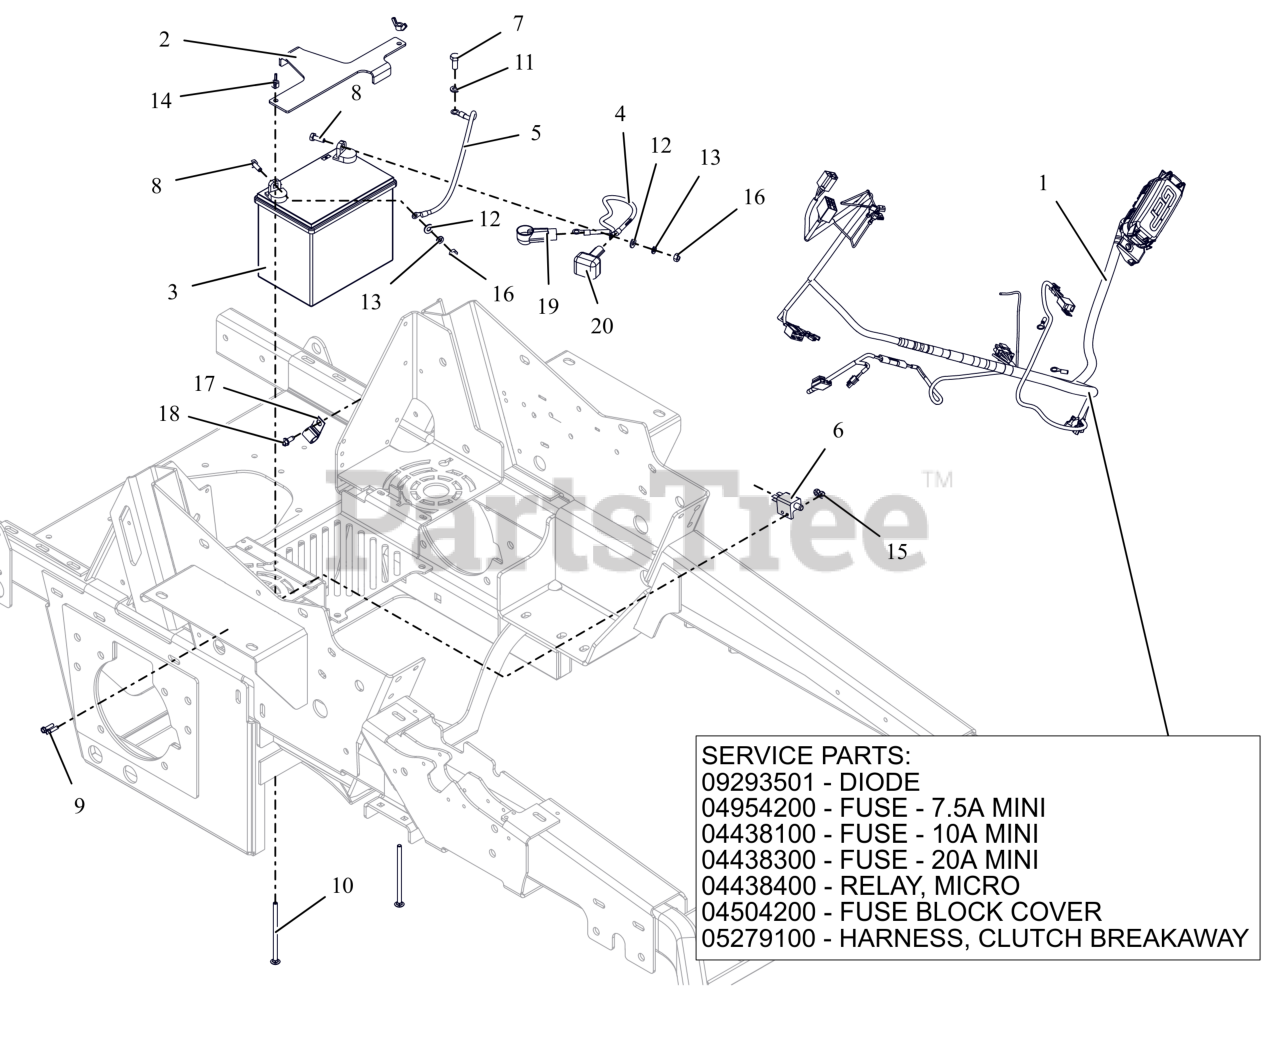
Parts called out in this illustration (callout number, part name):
1	HARNESS- WIRE PT300 MAIN
1	DIODE, CONNECTOR SHELL
1	FUSE, 7.5 AMP MINI-ATC
1	FUSE,10 AMP MINI-ATC
1	FUSE,20 AMP MINI ATC
1	RELAY,MICRO5 TERML W/RESISTOR
1	COVER, HARNESS FUSE/RELAY MOD
1	HARNESS, CLUTCH BREAKAWAY
2	HOLDDOWN- BATTERY
3	BATTERY, 300 CCA 10U1L
4	CABLE, STARTER 13.00"
5	CABLE-GROUND .25 X 13.00 X .31
6	SWITCH- DOUBLE POLE N.O./N.O.
7	BLT, HEX M8-1.25X20 G8.8 ZCC
8	BLT, HEX .25-20X.75 G5 ZCC
9	BLT, HWH #10-24X.75 ZCC
10	BLT, RHSN .25-20X4.50 G5 ZCC
11	WSHR,LK-REG .312X.078 ZCC
12	WSHR,FLT .281X.625X.065 ZCC
13	WSHR,LK-REG .250X.062 ZCC
14	NUT, LK-WING .25-20 ZCC
15	NUT-LK-NYL #10-24 G2 ZCC
16	NUT-STD .250-20 G2 ZCC
18	SCR,TAP .25-20X.625 HWH ZCC
19	BOOT, .65ID POS
20	INSULATOR
